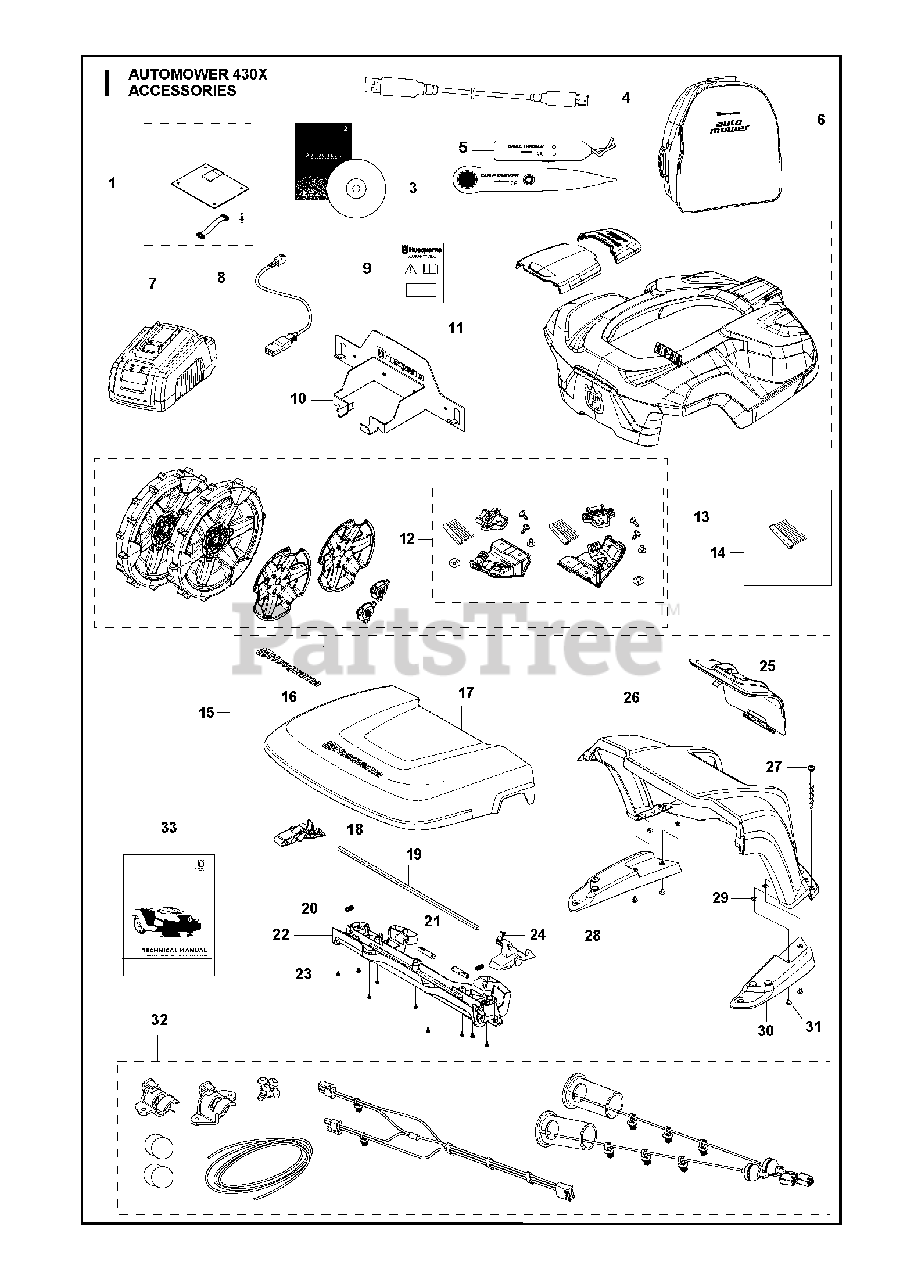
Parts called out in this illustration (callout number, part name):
1	GPS MODULE 315 430X
3	DVD Autocheck, Exp Ser
4	CABLE WHITE ALT GREY
5	TEST EQUIPMENT
6	BAG
7	CHARGER BATTERY TEST
8	CABLE ASSY QUICK CHARGER
9	LABEL WARRANTY SEAL DEALER
10	MISC. BLISTER WALL HA
11	White Body Kit, 430
12	BRUSH KIT 430450
13	Rear Wheel Kit with Brush
14	WHEEL BRUSH REFILL KIT
15	430450 HOUSE KIT
16	DECAL.HUSQVARNA.210MM
17	KIT LID - AUTOMOWER HOUSE
18	HANDLE RELEASE LEFT
19	ROD
20	SPRING SPRING CAP
21	HINGE PIN
22	BEAM
23	SCREW 14MM
24	HANDLE RELEASE RIGHT
25	HATCH
26	COVER BASE P2 HOUSE
27	SCREW KIT CS
28	SUPPORT BASE LEFT
29	NUT
30	SUPPORT BASE RIGHT
31	SCREW IHPANM M6X25 4.6 ZP-BC
32	430 HEADLIGHT KIT
